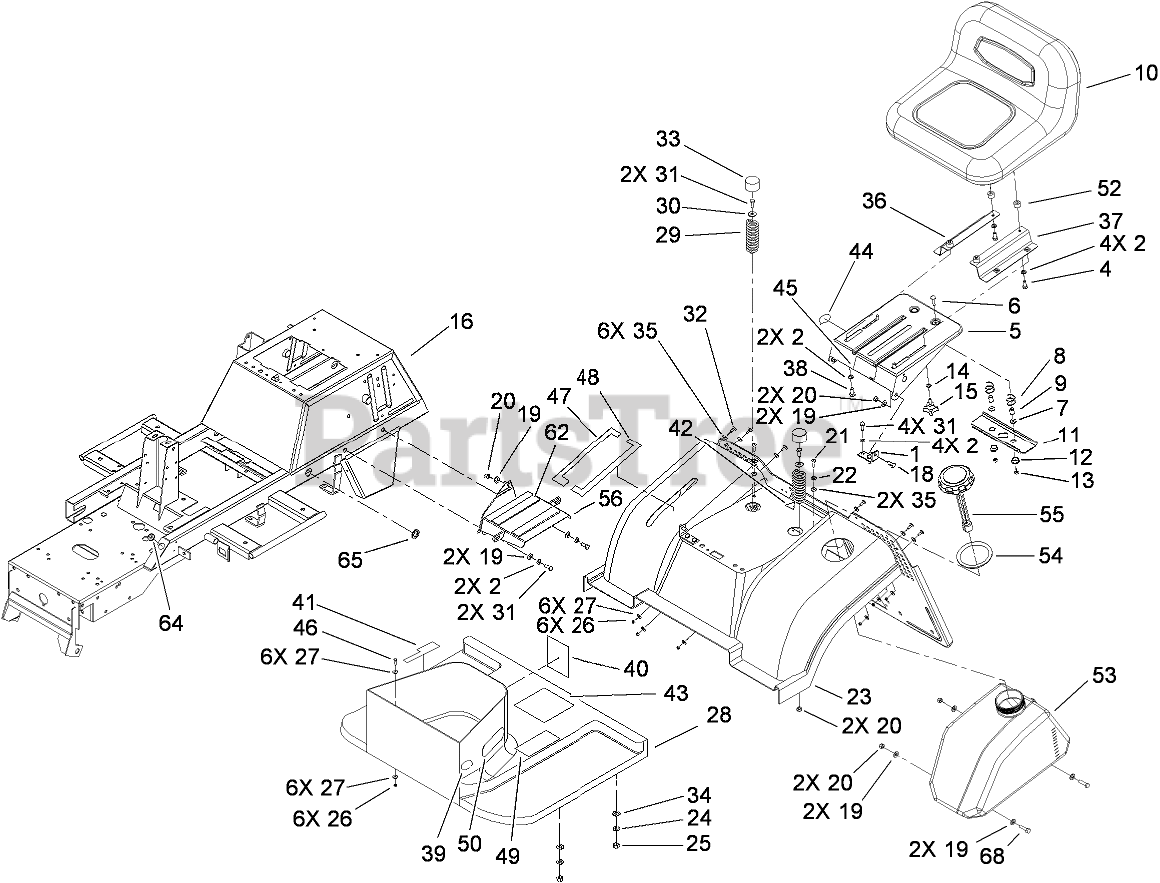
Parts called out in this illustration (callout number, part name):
1	BRACKET-SUPPORT, SEAT
2	WASHER-LOCK, SPRING
4	SCREW-HH
5	SUPPORT-SEAT
6	BOLT-CARRIAGE
7	WASHER-FLAT
8	SPRING-SEAT
9	SPACER-SPLIT
10	SEAT ASM
11	BRACKET
12	BUSHING
13	NUT-LOCK
14	WASHER-SPRING
15	KNOB-ADJUSTMENT
16	CHASSIS-FRAME
18	SCREW-SUPPORT, SEAT
19	WASHER-PLAIN
20	NUT-LOCK, NI
21	SCREW-HSFH
22	WASHER-FINISH
23	FENDER-BODY, REAR
24	WASHER-FLAT
25	NUT-LOCK, NI
26	NUT-LOCK
27	WASHER-FLAT
28	FOOTREST ASM
29	SPRING-SEAT
30	WASHER-PLAIN
31	SCREW-HH
32	BOLT-CARRIAGE
33	CAP-HUB
34	WASHER-RUBBER
35	WASHER-RUBBER
36	BRACKET-SEAT, RH
37	BRACKET-SEAT, LH
38	Screw
39	DECAL-BRAKE, PARKING
40	DECAL-STARTING
41	DECAL-OPERATION, HYDRO
42	DECAL-BAG TO FRAME
43	DECAL-INSTRUCTION
44	DECAL-SWITCH
45	DECAL-DANGER
46	SCREW-HH
47	DECAL-HOC, LH
48	DECAL-HOC, RH
49	DECAL-OPERATION
50	DECAL-TOWER
52	SHIM-SEAT
53	TANK-FUEL
54	PROTECTOR-NECK, FILLER
55	CAP-FUEL
56	BRACKET-FUEL, TANK
62	STRIP-RUBBER, FUEL TANK
64	GROMMET
65	GROMMET
68	SCREW-HH
